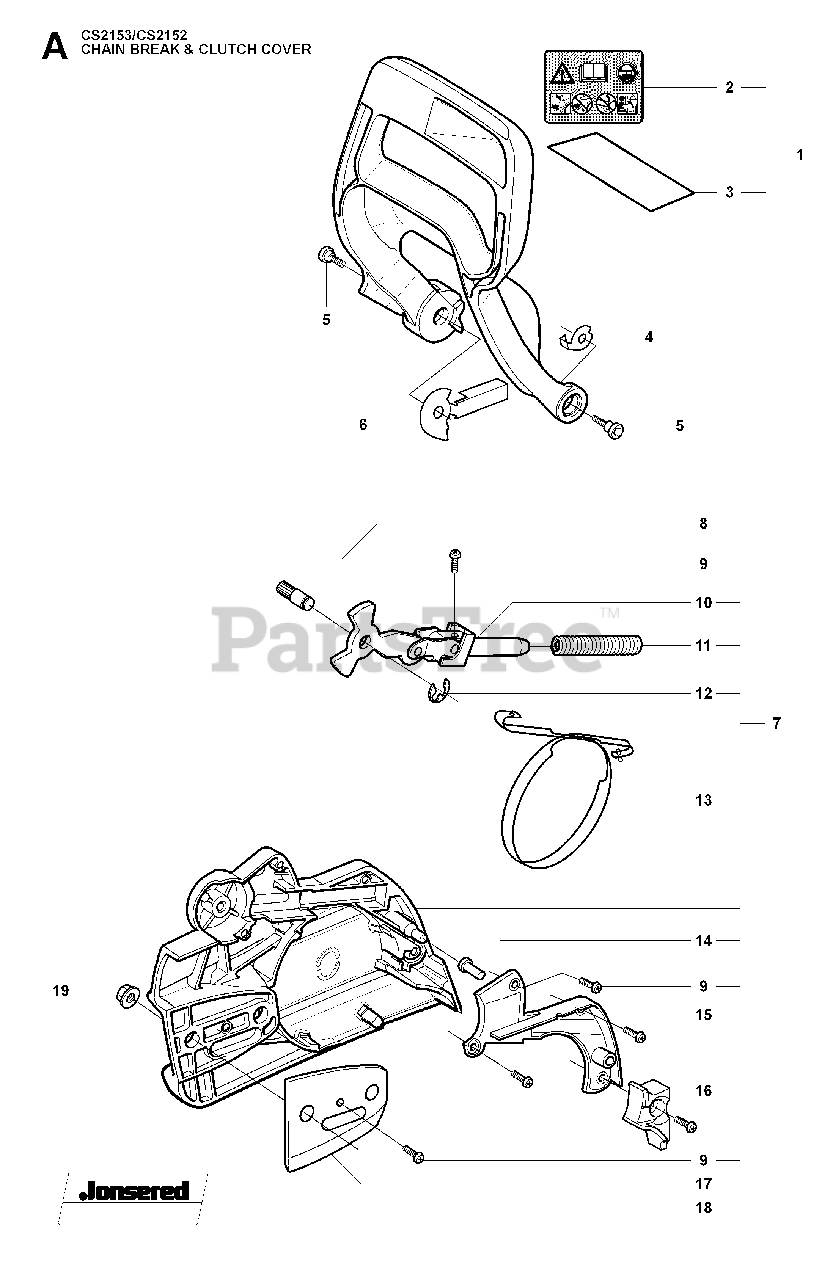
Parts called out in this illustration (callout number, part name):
1	HAND GUARD
3	PROTECTOR
6	PROTECTOR
7	CHAIN BRAKE
13	BRAKE BAND
16	PROTECTOR
19	NUT M8 FLANGE
